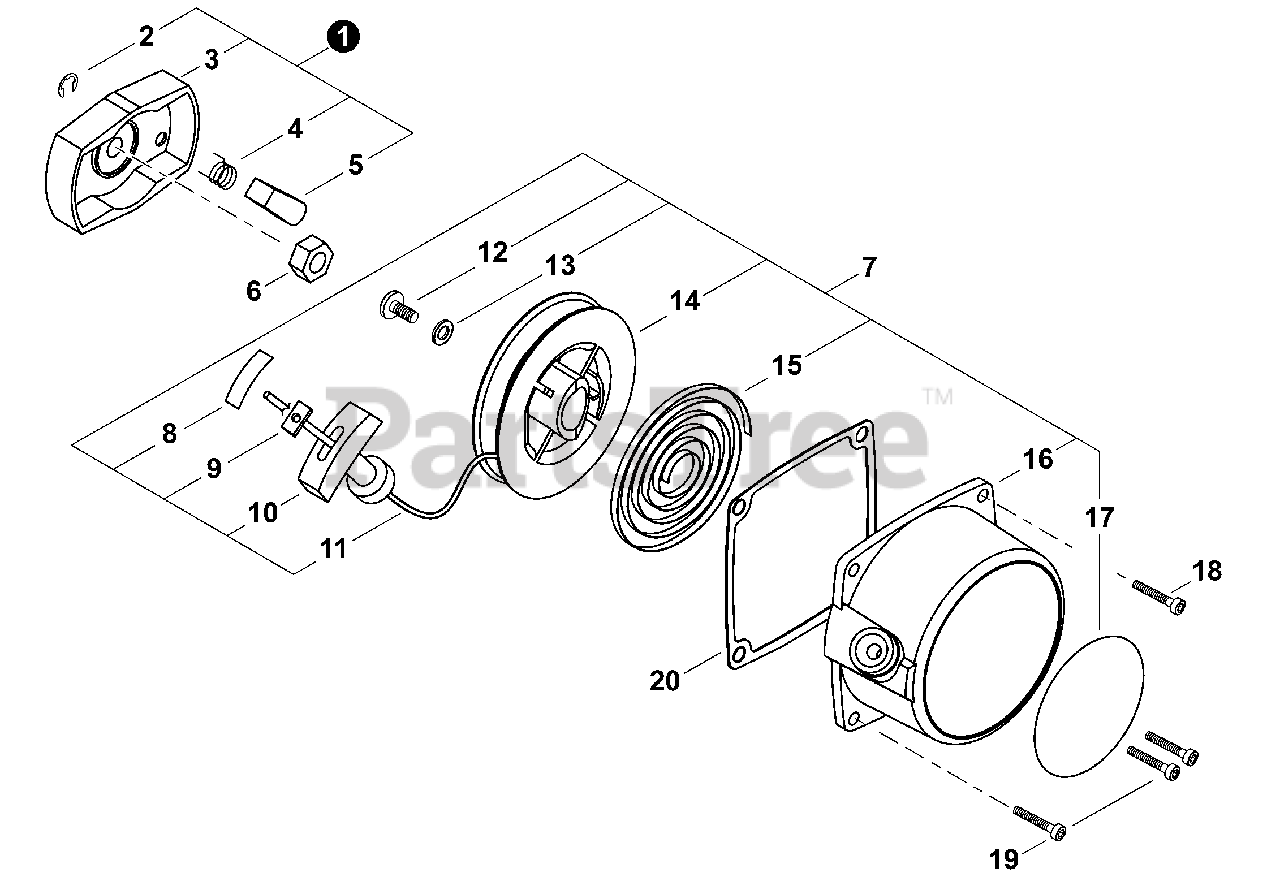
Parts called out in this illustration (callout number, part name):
1	PULLEY ASSY, STARTER
2	E-RING 4
3	PULLEY, STARTER
4	SPRING, RETURN
5	PAWL, STARTER
6	NUT M8×H5
7	STARTER ASSY, RECOIL
9	RETAINER, ROPE
10	GRIP, STARTER
11	ROPE, STARTER
12	SCREW 5
13	WASHER
14	REEL, ROPE
15	SPRING, RECOIL
16	CASE, RECOIL STARTER
17	LABEL, TRADE
18	BOLT M4×20
19	BOLT M4×16
20	GASKET, RECOIL STARTER
